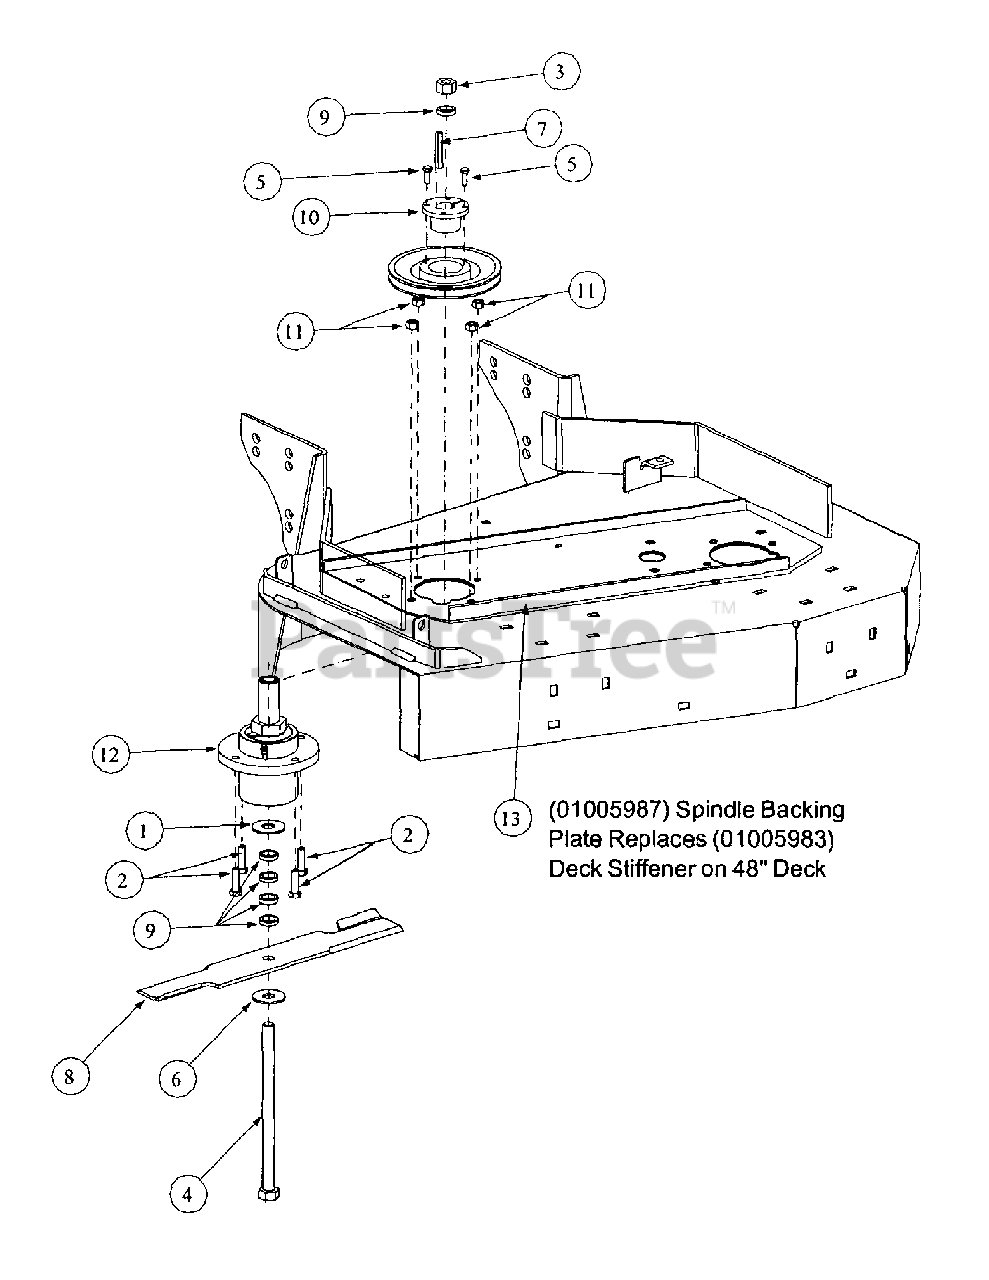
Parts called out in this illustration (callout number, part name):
1	Flat Washer, 1-1/2 x 5/8 x .05
2	Hex Cap Screw, 3/8-16 x 1-1/4
3	Hex Nut, 5/8-11
4	Hex Cap Screw, 5/8-11 x 9-1/2
5	Hex Cap Screw, 1/4-20, .75
6	Flat Washer, 5/8 Zinc
7	Key Stick, 1/4 x 1/4 x 2
8	Rotary Blade, 16-1/2
9	Blade Spacer, 5/8 ID, 1/4 Thick
10	Bushing
11	Lock Nut, 3/8-16
12	Spindle Assembly
13	Deck Plate 32" Deck
13	Deck Stiffener 48" Deck
